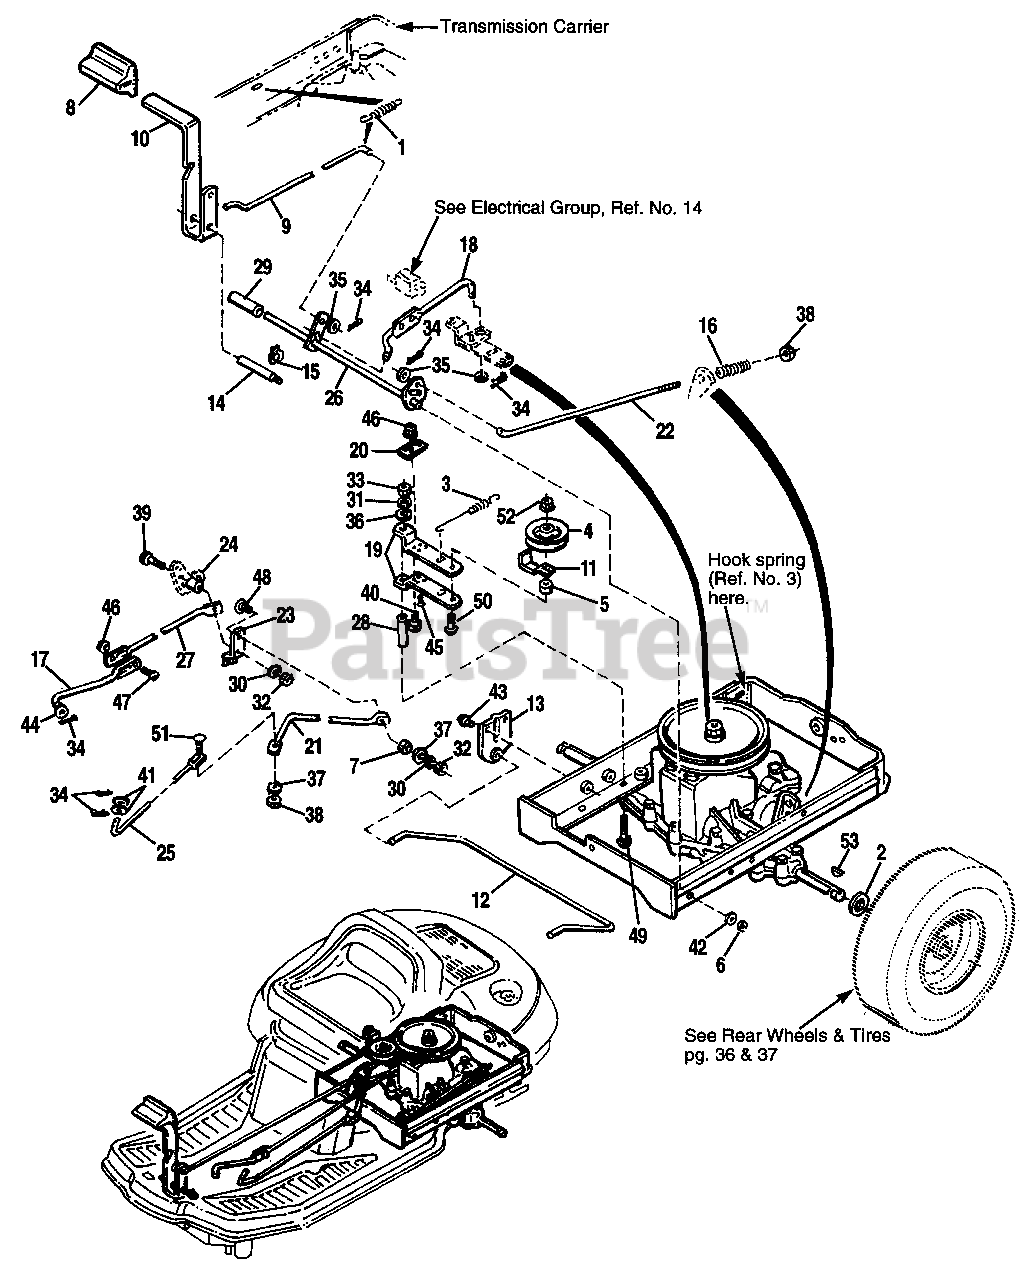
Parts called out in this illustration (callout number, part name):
1	SPRING, Return
2	WASHER, 3/4
4	PULLEY, Idler
5	SPACER, 25/64 x 5/8 x 11/16
6	KLIPRING, 1/2
8	PAD, Pedal
9	ROD, Clutch, Front
10	LEVER, Clutch
11	GUARD, Spring
12	TORSION BAR
13	BRACKET, Torsion Bar
14	PIVOT, Brake
15	KLIP RING, 3/4
16	SPRING, Compression
17	ROD, Return, Front
18	ROD, Clutch, Rear
19	CLEVIS, Idler Bracket
21	ROD, Control
23	LEVER, Control
25	ROD, Shift, Front
26	PIVOT SHAFT ASSY.
27	ROD, Return, Rear
28	SPACER, Pivot
30	LOCKWASHER, 5/16
31	LOCKWASHER, 5/16
32	NUT, Hex, 5/16-18
33	NUT, Hex, 5/16-18
34	COTTER PIN, 7/64 x 3/4
35	WASHER, Plain
36	WASHER, Plain
37	WASHER, Plain, 5/16
38	NUT, Hex, Lock, 5/16-18
39	CAPSCREW, 5/16-18 x 1-3/4
40	CAPSCREW, Hex, 1/4-20 x 3/4
41	WASHER, Plain, 1/2 x 1 x 1/32
42	WASHER, Plain
43	SCREW, Taptite, 5/16-18 x 1/2
44	WASHER, Plain, 13/32 x 7/8 x 5/64
45	SCREW, Taptite, 1/4-20 x 5/8
46	NUT, Hex, Flange Whiz, 1/4-20
47	CARRIAGE BOLT, 1/4-20 x 7/8
48	CARRIAGE BOLT, 5/16-18 x 1
49	CARRIAGE BOLT, 5/15-18 x 2-3/4
50	CARRIAGE BOLT, 3/8-16 x 2-/1/4
51	CARRIAGE BOLT, 5/16-18 X 1-1/4
52	NUT, Hex, Jam, Lock, 3/8-16
53	KEY
